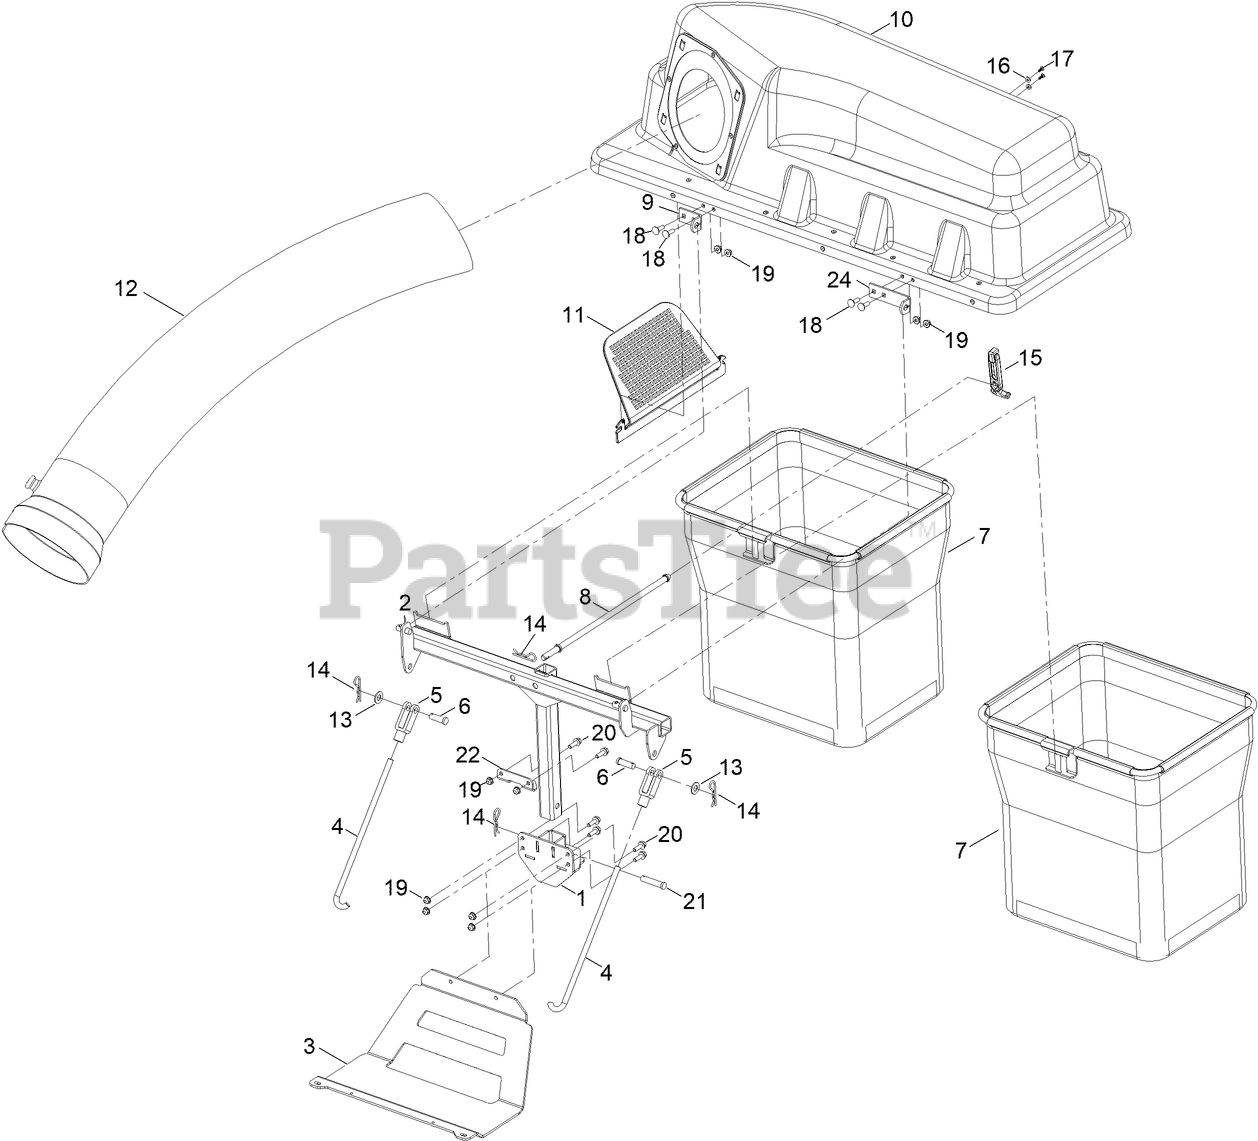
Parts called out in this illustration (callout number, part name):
1	MOUNT-BAGGER [BLACK]
2	FRAME-BAGGER [BLACK]
3	GUARD-MUFFLER [BLACK]
4	ROD-BAGGER SUPPORT
5	CLEVIS
6	PIN-CLEVIS
7	BAG ASM
8	ROD-HOOD, DOWN (HOLD)
9	BRACKET-HOPPER PIVOT
10	TOP ASM-BAGGER
11	SCREEN-BAGGER
12	TUBE-BAGGER
13	WASHER-FLAT
14	PIN-HAIR
15	LATCH-RUBBER
16	WASHER-PLAIN
17	SCREW-PLASTIC, PTH
18	BOLT-CARR
19	NUT-HF
20	SCREW-HHF
21	PIN-CLEVIS
22	PLATE-BAGGER STABILIZER
24	BRACKET-HOPPER PIVOT
